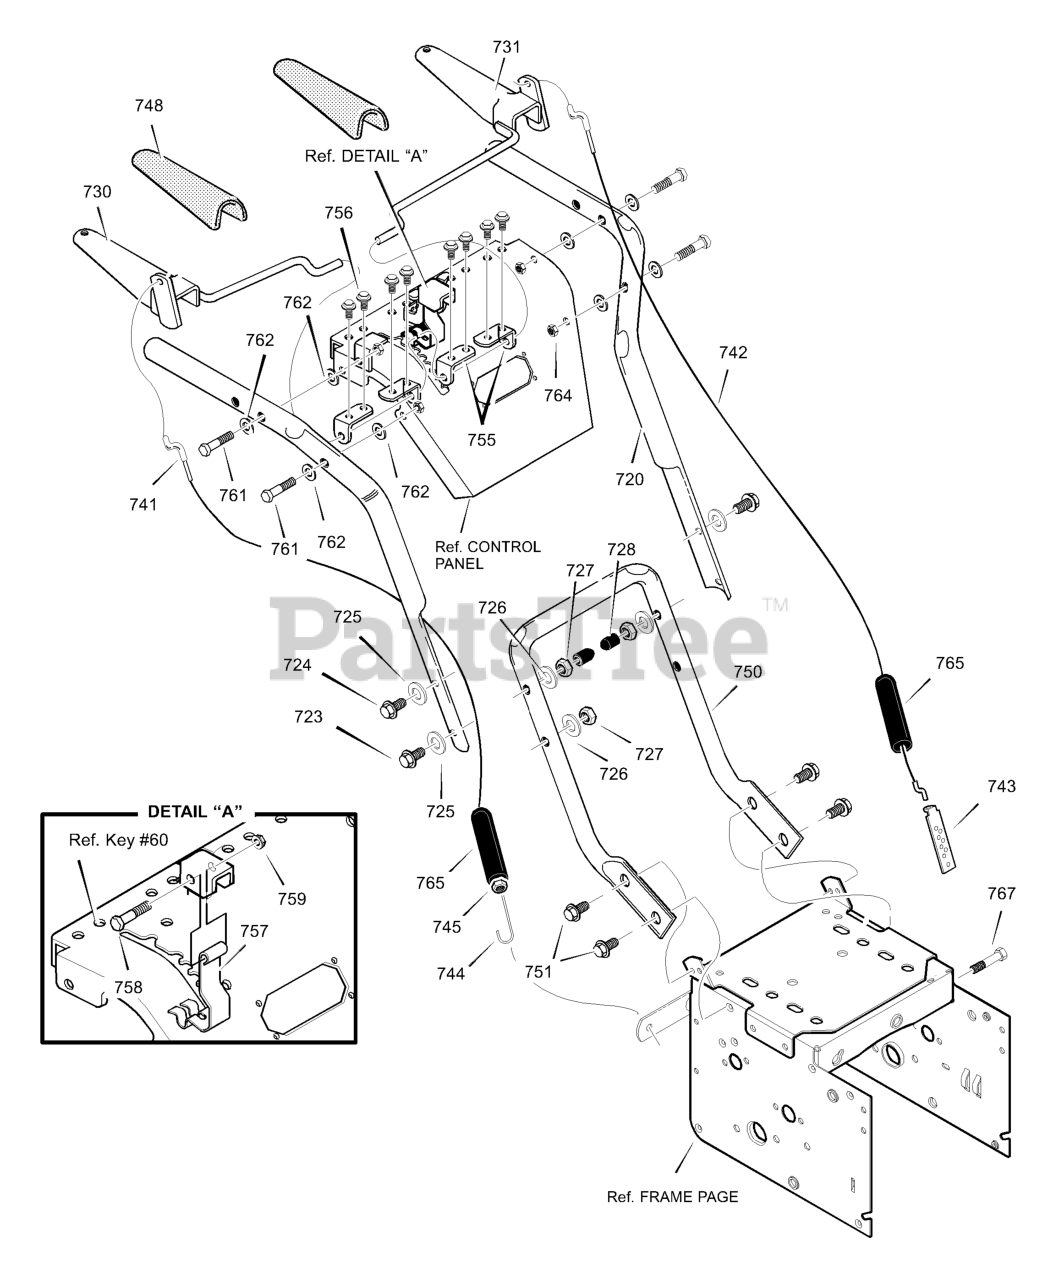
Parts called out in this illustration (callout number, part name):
720	HANDLE, UPPER LH
721	HANDLE, UPPER RH
723	SCREW
724	SCREW
725	WASHER, FLAT
726	WASHER, SPTLK
727	NUT, REGHEX
728	STOP, PLASTIC
730	LEVER, ASSY CLUTCH DRIVE RH
731	LEVER, ASSY CLUTCH DRIVE LH
741	CABLE, AUGER CLUTCH
742	CABLE, AUGER DRIVE
743	BRACKET, CABLE ADJUSTER
744	SPRING, AUGER CLUTCH
745	NUT, 1/4-20
748	GRIP, CLUTCH HANDLE
750	HANDLE, LOWER
751	SCREW
754	SCREW
755	BRKT, ROD
756	SCREW
757	SPRING, CAM LOCK
758	BOLT, HEX
759	NUT
761	SCREW
762	WASHER, FLAT
764	NUT, HEXFLNG
765	BOOT, CLUTCH SPRING
767	BOLT, HEX 1/4-20 X 1.50
